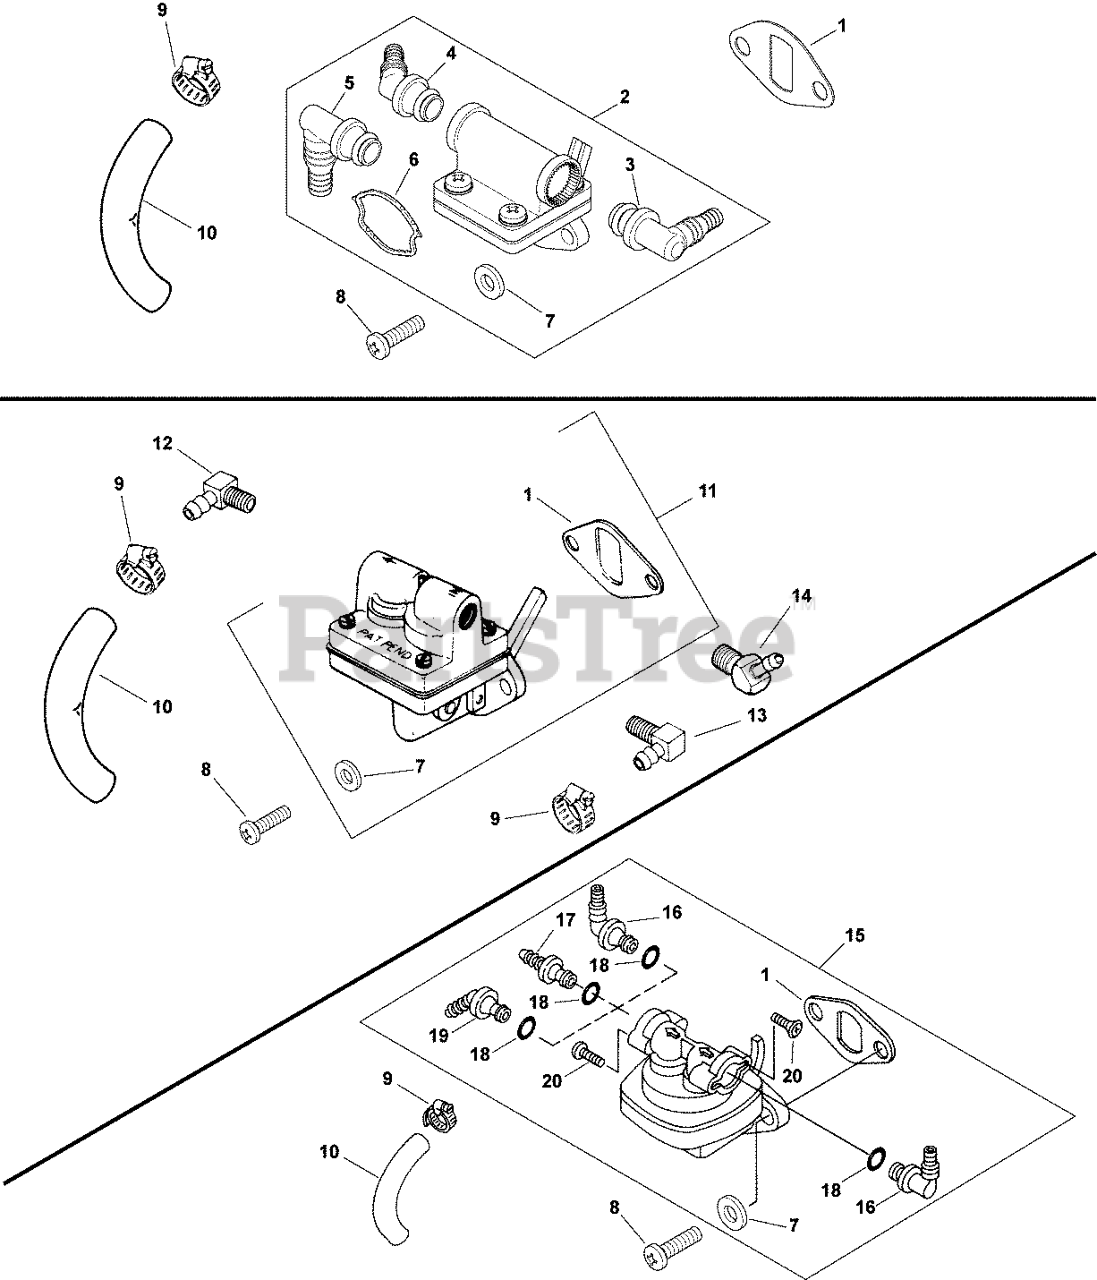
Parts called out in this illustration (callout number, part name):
1	GASKET, FUEL PUMP
2	KIT, FUEL PUMP
3	KIT, 3/16" FITTING, (90 DEG.)
4	KIT, 3/16" FITTING, (45 DEG.)
5	KIT, 90 DEG. FITTING
6	O-RING, FUEL PUMP
7	WASHER, FLAT 1/4" (O.D. 1/2")
8	SCREW, SEMS 1/4-20X3/4"
9	CLAMP, HOSE (KM)-USE 25 237 31-S
10	LINE, FLEXIBLE FUEL - DISCONTINUED
11	FUEL PUMP
12	CONNECTOR, 90 DEG. - DISCONTINUED
13	CONNECTOR, 90 DEG. HOSE
14	CONNECTOR, 45 DEG.
15	FUEL PUMP
16	CONNECTOR, 90 DEG. W/O-RING-DISC.
17	CONNECTOR,STRAIGHT W/O-RING-DISC.
18	O RING FITTING - DISCONTINUED
19	CONNECTOR, 45 DEG. W/O-RING-DISC.
20	SCREW, LBD SCKT PAN - DISC.
